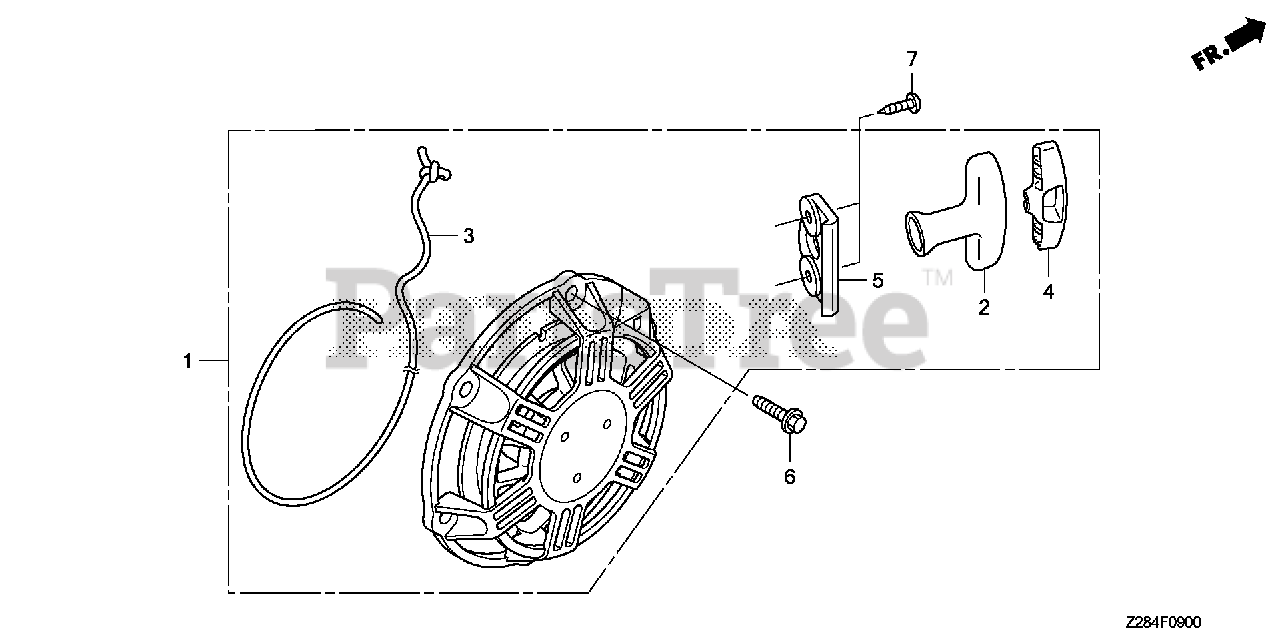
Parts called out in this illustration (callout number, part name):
1	STARTER ASSY., RECOIL (COO)
2	GRIP, STARTER (COO)
3	ROPE, RECOIL STARTER
4	COVER, GRIP
5	GUIDE, STARTER ROPE
6	BOLT, FLANGE (6X20) (CT200)
7	SCREW, TAPPING (5X16) (PO)
